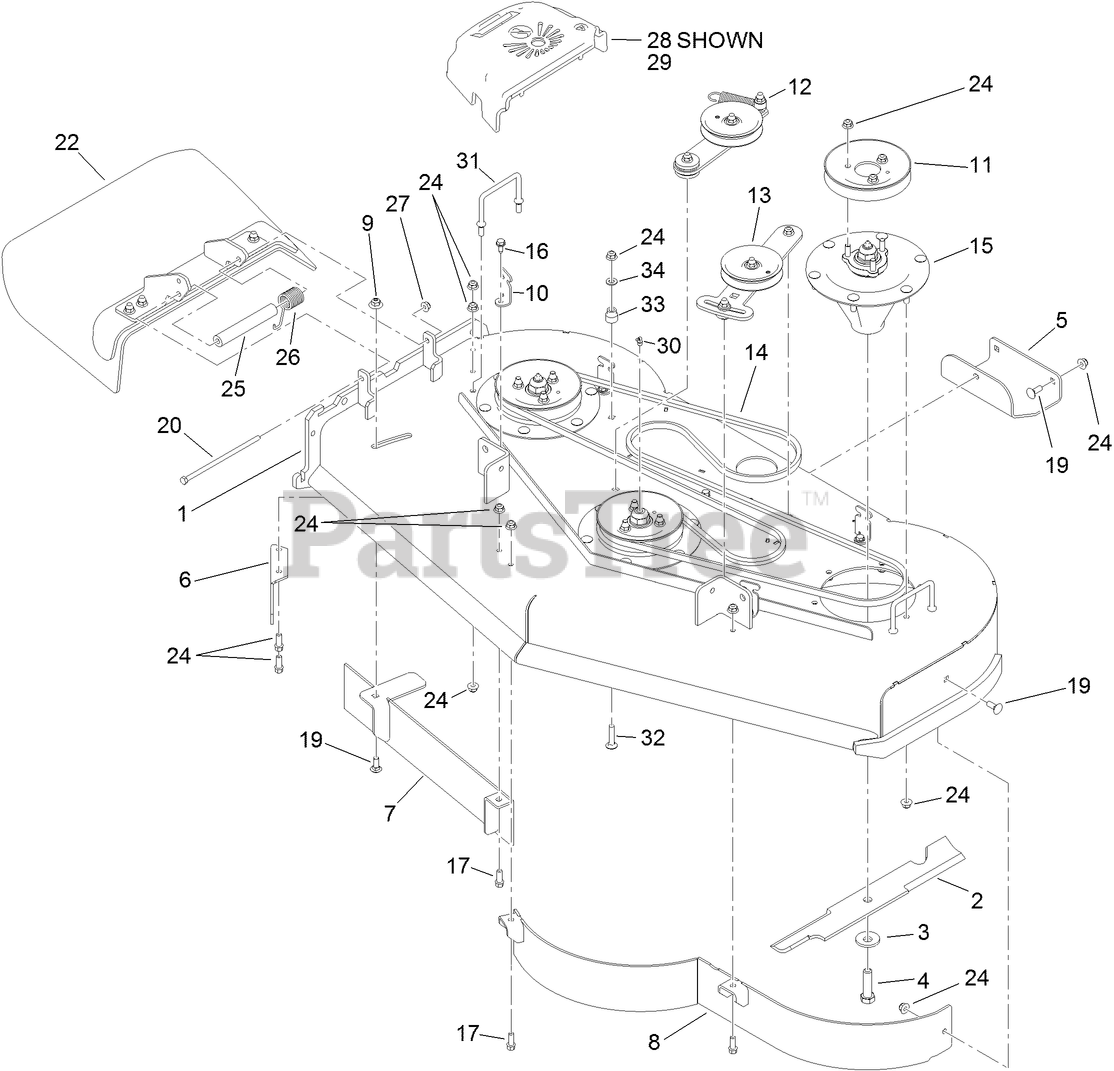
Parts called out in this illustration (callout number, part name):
1	DECK ASM
2	BLADE-18IN, HI FLOW
3	Washer-Blade Bolt, Heavy
4	SCREW-BLADE
6	BAFFLE-DISCHARGE
8	BAFFLE-52 INCH
9	NUT-FLANGE, NI
10	BRACKET-COVER
11	PULLEY
12	IDLER ARM ASM
13	IDLER ADJUST ASM
14	BELT-V
15	SPINDLE ASM
16	SCREW-HWHTF
17	SCREW-HWH
19	BOLT-CARR
20	SCREW-HH
22	DEFLECTOR ASM
24	NUT-HF, NI
25	SPACER
26	SPRING-TORSION
27	NUT-HF, NI
28	COVER-BELT, RH
29	COVER-BELT
30	FITTING-GREASE
31	WIREFORM-COVER
32	SCREW-CARR
33	BUSHING-IDLER
34	WASHER-FLAT
